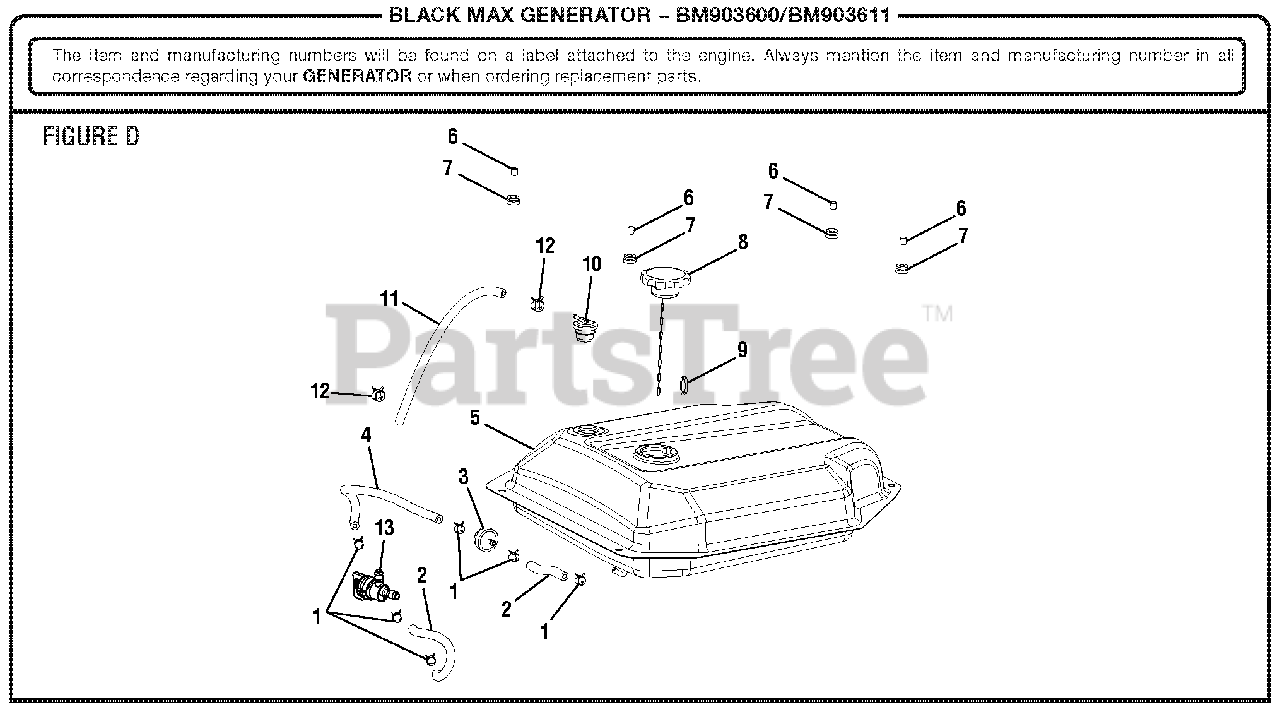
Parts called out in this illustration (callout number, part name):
1	Fuel Line Clamp (1/2 in.)
2	Fuel Hose (90 mm)
3	Fuel Filter Inline (1/4 in.)
4	Fuel Hose (120 mm)
5	Fuel Tank
9	Ring Clip
10	Vapor Vent
11	Vapor Hose (330 mm)
12	Fuel Line Clamp (7/16 in.)
13	Fuel Shut Off Valve
